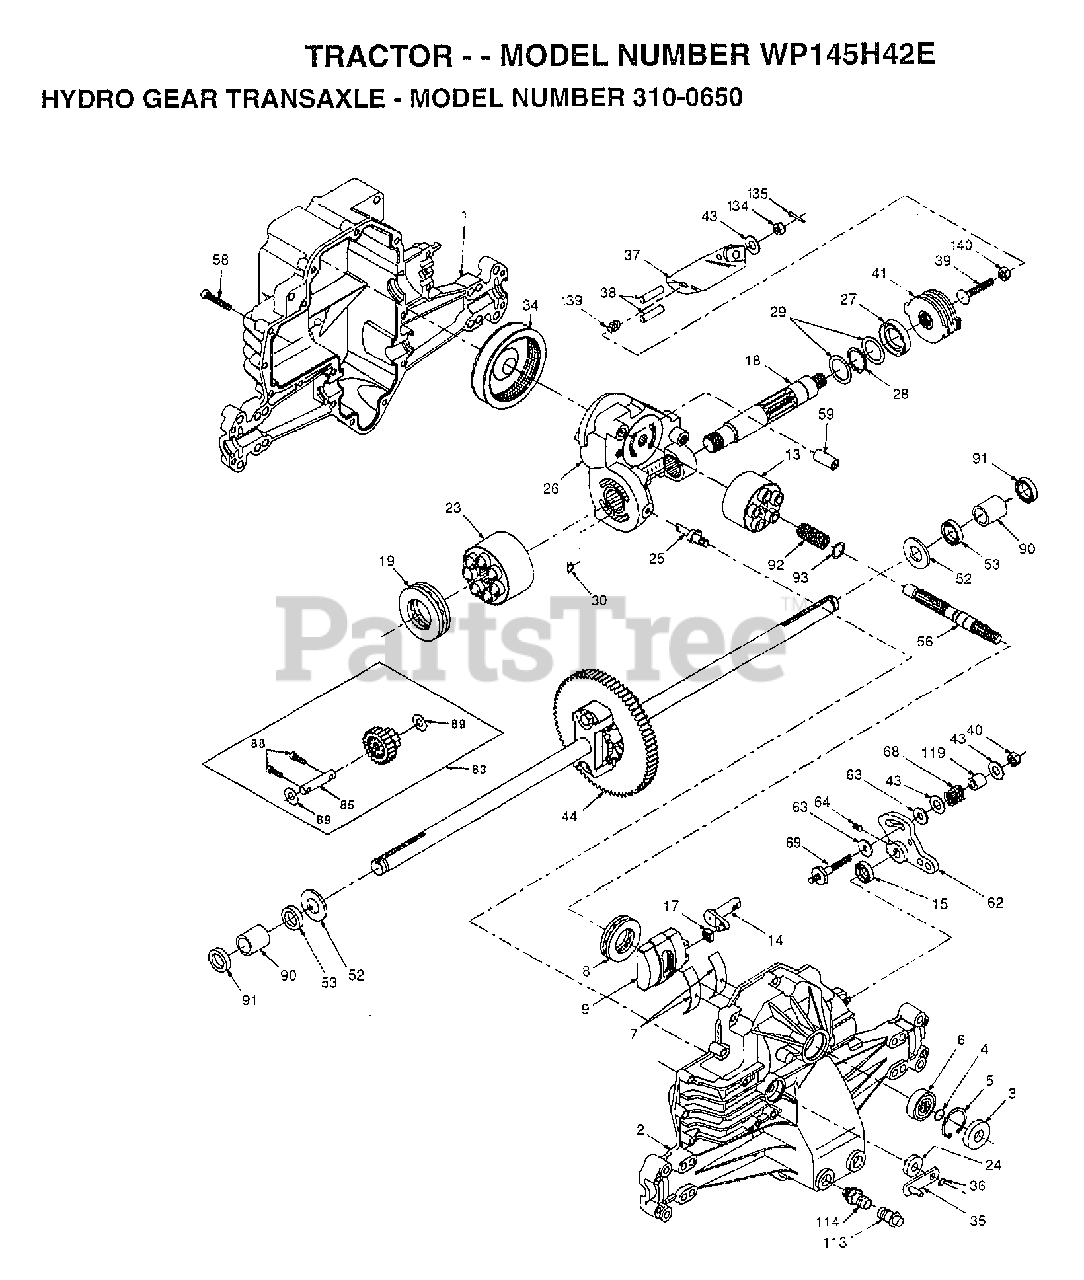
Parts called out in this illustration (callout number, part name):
1	HOUSING.L.50074RM
2	HOUSING.UP.70125
3	SEAL.9008000-0128
4	RING.RET.2003016.
5	RING.RET.2003052.
6	BEARING.(50552)42X68X16
7	CRADLE- 2003023.
8	BEARING.THU.50551
9	SWASHPLT.2003087.
13	BLOCK.CLYN.70079.
14	ARM.TRUN.2003005.
15	SEAL.9008000-0126
17	GUIDE.2000015.
18	SHAFT.MOTOR.50449
19	BEARING.THU.50552
23	BLOCK.CYLIN.70082
24	SEAL.LIP.45074
25	ACTUATOR.2003555
26	KIT.CEN.SEC.70250
27	SEAL.LIP.45075
28	RING RETAIN 50007
29	WASHER.44872
34	ELEMENT.OIL.44964
35	ARM.BYPASS.50270
36	RING.RETAIN.44870
37	ARM.ACTUAT.23710
38	PIN.ACTUAT.44891
39	BOLT.50316
40	NUT.LOCK.HX.50317
41	KIT.BRAKE.70135
43	WASHER HYD 44130
44	DIFFRENTIAL.70226
52	WASHER.HYD.44875
53	SEAL.HYDRO.45076
56	SHAFT.INPUT.50005
58	BOLT.1/4-20.44876
59	PIN.HYDRO.50002
62	ARM.CONTROL.50254
63	PUCK.DAMPER.50281
64	SCREW.SET.50018.
68	SPRING.HYD.50277
69	STUD.5/16-24.DANA
83	JACKSHAFT/PINION GEAR.70132
85	PIN.SHAFT 50559
88	SCREW.CAP.50154.
89	WASHER.HYD.50132
90	BEARING.SLV.50118
91	SEAL.WIPER.50941
92	SPRING.2003014.
93	WASHER.2003017
113	CAP.VENT.70109
114	O-RING.ASM.70110
119	SPACER.HYD.50278
134	NUT.CAS.HYD.44142
135	PIN.COT.HYD.44101
139	SPRING.COMP.50431
140	NUT.HEX.50269
